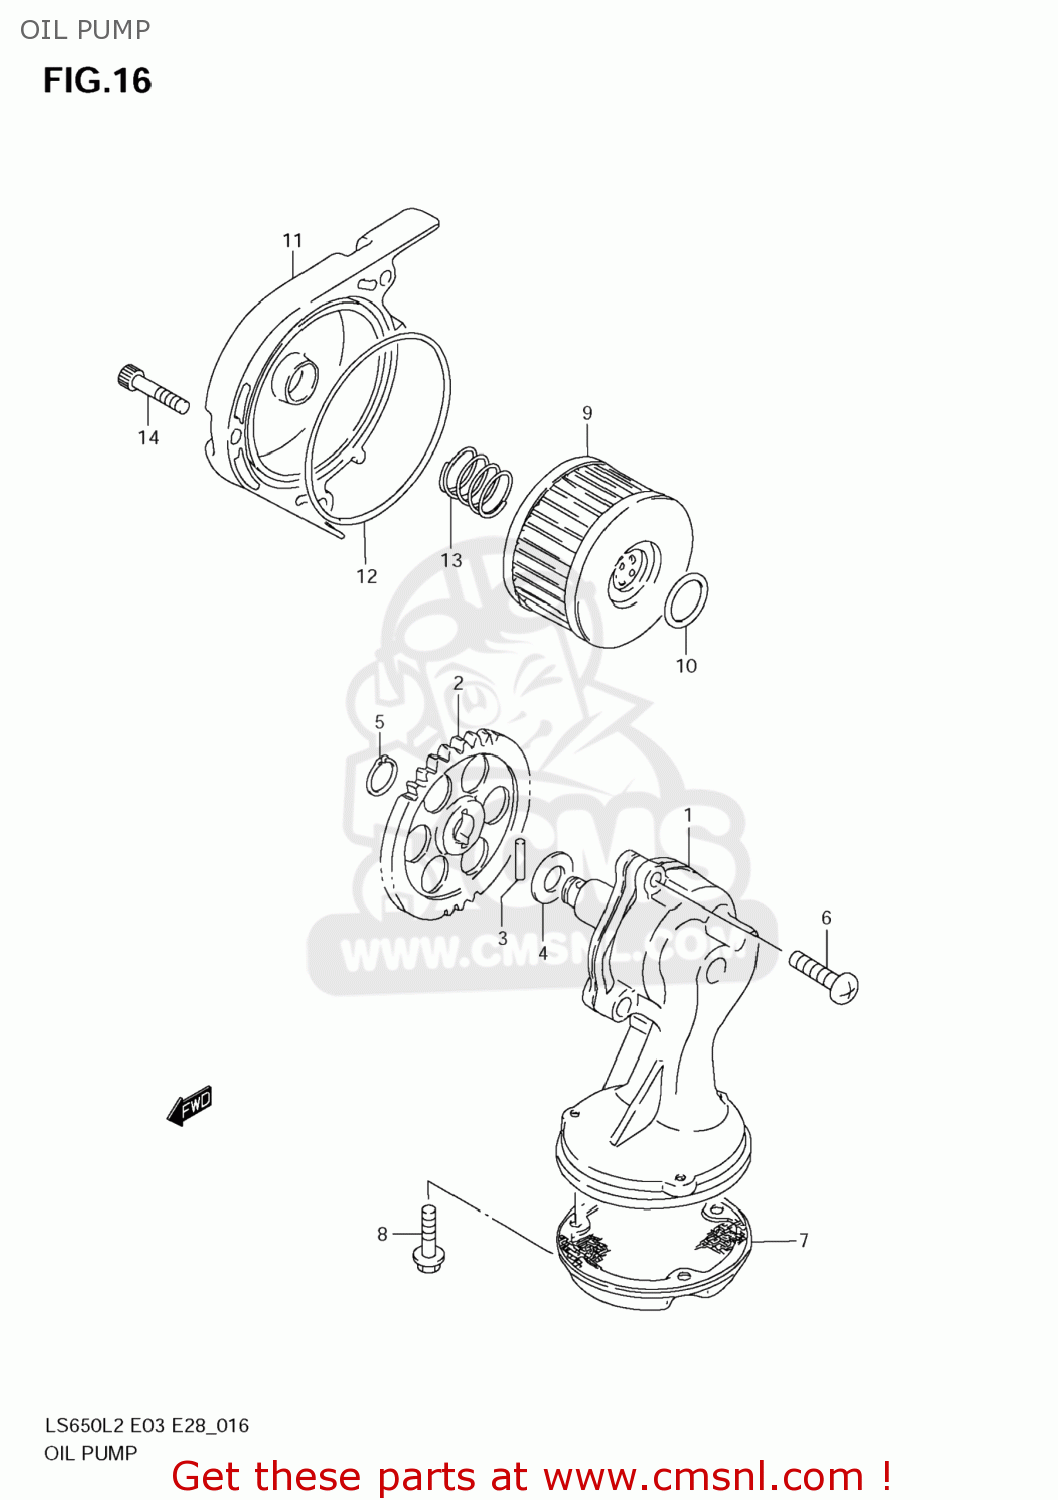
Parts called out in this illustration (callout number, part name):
1	PUMP ASSY,ENGINE OIL
2	GEAR,ENG OIL PUMP DRIVEN
3	PIN(4X15.8)
4	SHIM(10X18X0.5)
5	CIRCLIP
6	SCREW
7	STRAINER,ENGINE OIL
8	BOLT
9	FILTER ASSY,ENGINE OIL
10	O RING(D:2.4,ID:15.8)
11	CAP,OIL FILTER
12	O RING(D:2.4,ID:73)
13	SPRING
14	BOLT(6X25)
